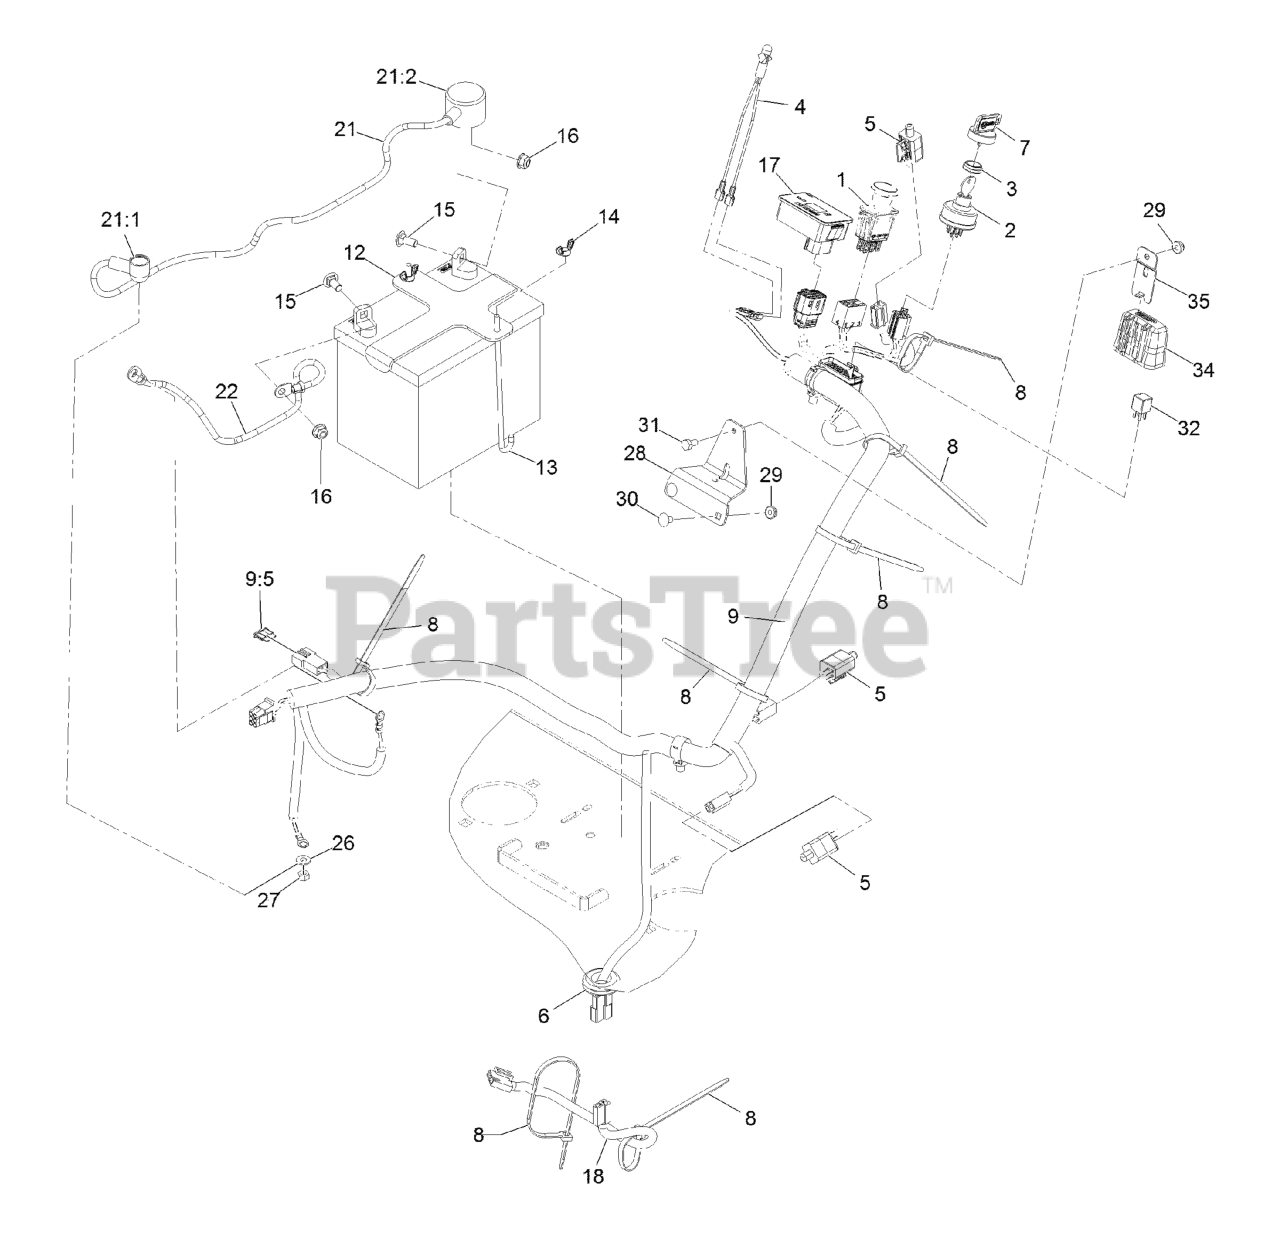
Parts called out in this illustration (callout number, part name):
1	SWITCH-PTO
2	SWITCH, KEY START
3	NUT-SWITCH, IGNITION
4	INDICATOR-LED, RED
6	GROMMET
7	KEY-IGNITION
8	TIE-PLASTIC
9	HARNESS-WIRE
9:5	FUSE-BLADE TYPE, 20 AMP
12	BRACKET, BATTERY HOLD DOW
13	BOLT-HOLDDOWN
14	WINGNUT
15	BOLT-CARR
16	NUT-HF, NI
17	MODULE-HOUR METER
18	HARNESS-CLUTCH PIGTAIL
21	POSITIVE BATTERY CABLE AS
21:1	INSULATOR-SOLENOID
21:2	INSULATOR-BATTERY
26	WASHER-FLAT
27	NUT-HEX
28	BRACKET-MOUNTING, FUSEBLO
30	SCREW-CARR
31	SCREW-HH
32	RELAY-MICRO
34	COVER-BLOCK, FUSE
35	CLIP-MOUNTING
